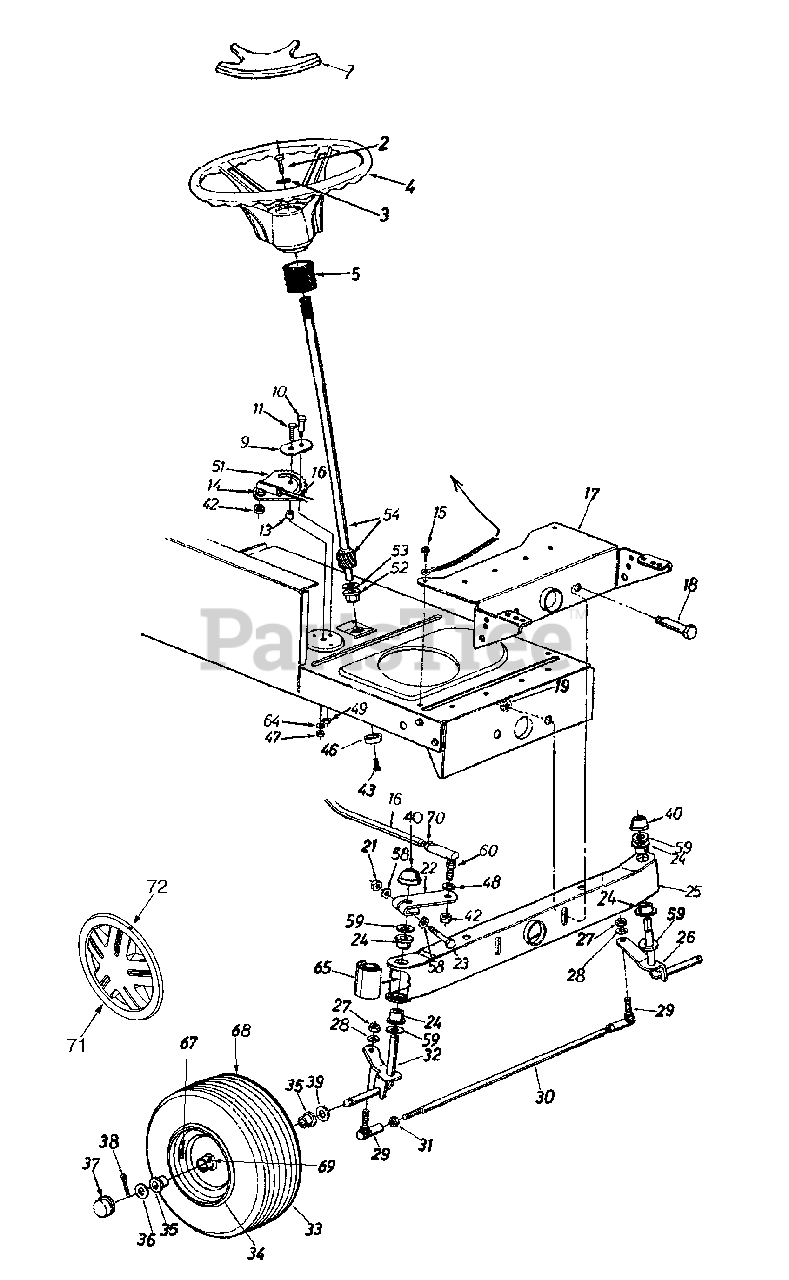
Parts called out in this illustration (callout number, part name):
1	Steering Wheel Cap
2	Hex Bolt 5/16-18 x 1" Lg.
3	Belleville Wash. .345" I.D.
4	Steering Wheel
5	Steering Bellow - 9"
9	Retainer Plate
10	Shoulder Bolt .437" Dia. x .35 Lg. 5/16-18 Thd.
11	Hex Bolt 3/8-24 x 1.0" Lg. (Gr. 5)
13	Spacer .380" I.D. x .625" O.D. x .227
14	L-Wash. 3/8" I.D. (H.D.)
15	Hex Wash. Hd. Self-Tap Scr.
16	Steering Drag Link
18	Shoulder Bolt .498" Dia. x 2.04 Lg. 3/8-16 Thd.
19	Flanged L- Nut 3/8-16 Thd.
21	Hex L-Nut 5/16-24 Thd.
22	Steering Arm Front Axle
23	Hex Bolt 5/16-24 x 2.00" Lg. (Gr.5)
24	Hex Flg. Brg. .632 I.D.
26	Front Axle Ass'y. - L.H.
27	Hex Nut 3/8-24 Thd.
28	L-Wash. 3/8" I.D.
29	Ball Joint 3/8-24 Thd.
30	Tie Rod (Adjustable)
31	Hex Jam Nut 3/8-24 Thd.
32	Front Axle Ass'y. - R.H.
36	Fl-Wash. .635 I.D. x 1.59" O.D.
37	Front Wheel Hub Cap
38	Cotter Pin 1/8" Dia. x 1.25"
39	Fl-Wash. .640 x 1.00 x 1.20
40	Push Cap 5/8" Dia. Rod
42	Hex Jam Nut 3/8-24 Thd.
43	Hex Patch Bolt 5/16-18 x .62"
46	Cap
47	Hex Cent. L-Nut 3/8-24 Thd.
48	L-Wash. 3/8" I.D.
49	Hex Cent. L-Nut 5/16-18 Thd.
51	Steering Gear Segment
52	Hex Flg. Brg. .634 I.D.
53	Fl-Wash. (Hardened)
54	Steering Shaft
58	Wave-Wash. .32" I.D. x .62" O.D.
59	Fl-Wash. (Hardened)
60	Drag Link Ball Joint 7/16-20 Thd.
64	Bell-Wash. .39" I.D. x 1.38" O.D.
65	Pivot Bar End Cap
67	Valve - Air
69	Grease Fitting
70	Jam Nut 7/16-20
71	Spoked Hub Cap (6" Dia.)
72	Spring Clip
